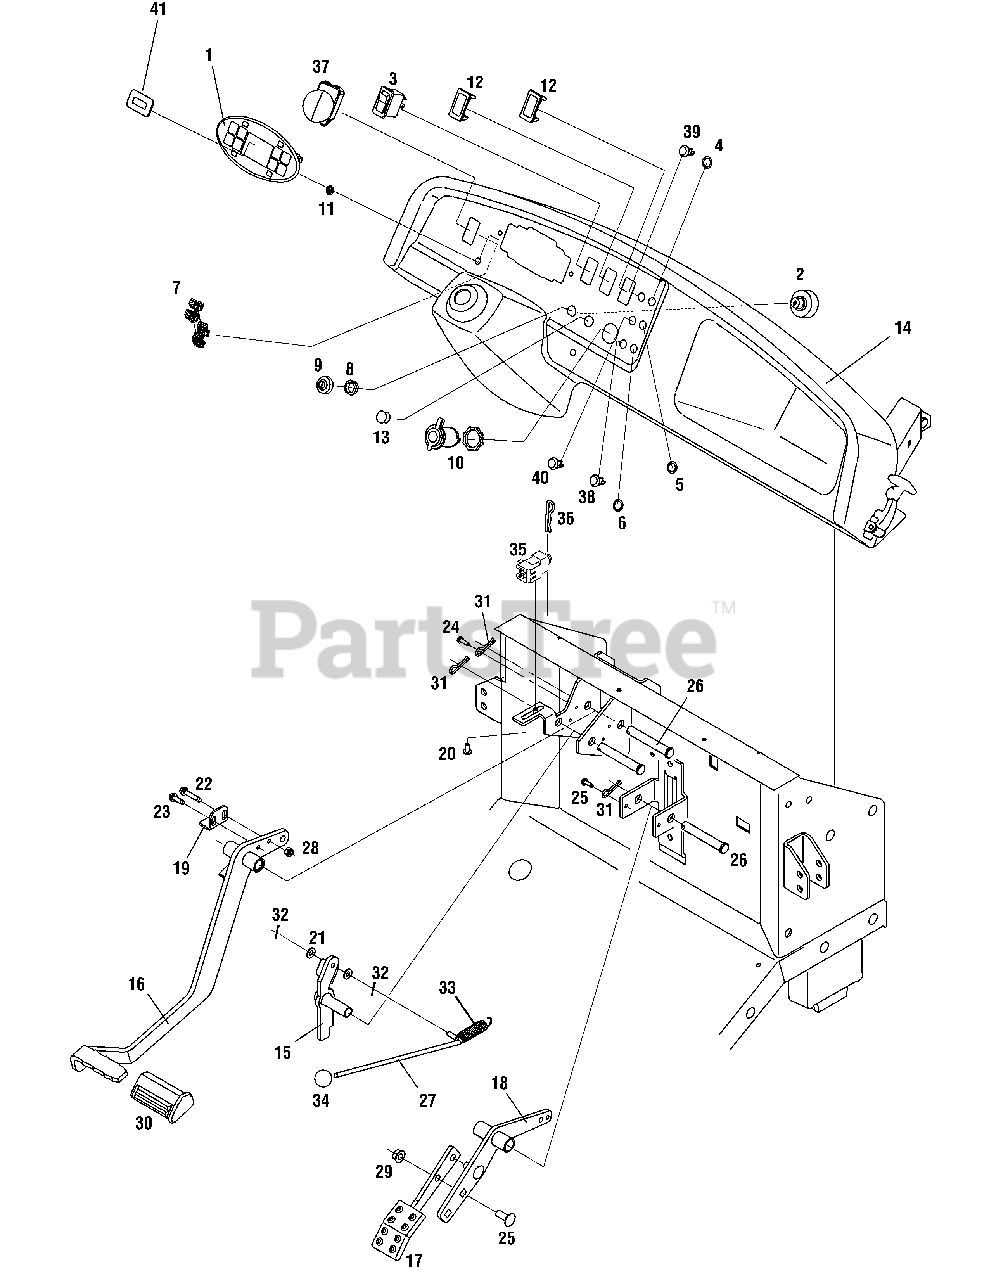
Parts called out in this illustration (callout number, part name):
1	Instrument Dash Cover
2	Switch, Key
3	Rocker Switch
4	Switch, Green
5	Switch, Yellow
6	Switch, Red
7	Accessory Harness, Diff Lock
8	Nut, Ignition Switch, 5/8-32
9	Cap, Ignition Switch
10	Power Receptacle, 12V
11	Nut, Retainer, 1/8
13	Plug, Horn Switch
14	Dash Panel Kohler
15	Lever , Parking Brake
16	Pedal Assembly, Brake
17	Pedal Assembly, Throttle
18	Pedal Arm Assembly, Throttle
19	Plate, Brake Switch
20	Screw, Hi-Lo, 1/4-20 x .5
21	Washer, Flat .25 x .630 x .0515
22	Screw, Self-Tapping, 1/4-20x1.25
23	Screw, Self-tapping, 1/4-20, .75
24	Screw, Self-tapping, #10-32 x .625
25	Bolt, Carriage, 3/8-16 x 1.0
26	Pin, Clevis .50 x 3.25
27	Rod, Brake Lock
28	Nut, Hexlock, 1/4-20 GR 8
29	Nut, Flange Lock, 3/8-16
30	Pad, Brake Pedal
31	Pin, Cotter, 5/32 x 1.0
32	Pin, Cotter, 1/16
33	Spring, Extension, .637 x 2.972
34	Knob, Ball
35	Snap Mount Switch, Interlock
36	Pin, Cotter.08 x 1.42
37	Differential Lock Switch
38	Red LED Indicator Light
39	Green LED Indicator Light
40	Yellow LED Indicator Light
41	Hour Meter Indicator
